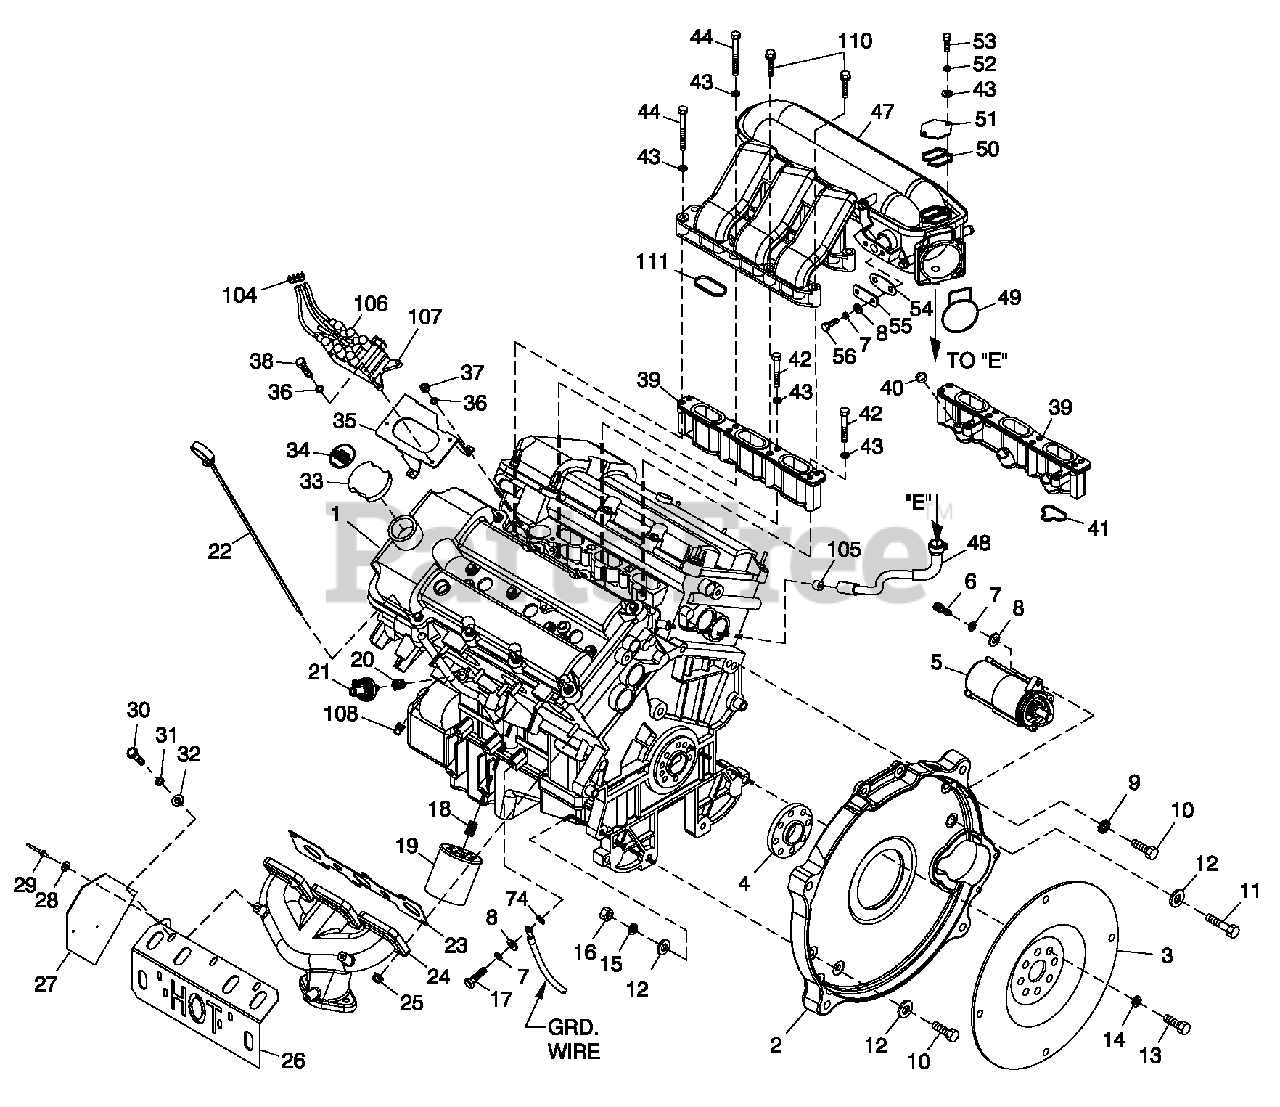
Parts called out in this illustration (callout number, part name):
1	ENGINE 3.0L G3 LS (RWD) MAKE
2	ADAPTER ENGINE
3	FLEX PLATE 2 POLE
4	SPACER FLEX PLATE
5	STARTER MOTOR 12V
6	SCREW SHC M8-1.25 X 30 G12.9
7	WASHERLOCK M8-5/16
8	WASHER FLAT 5/16-M8 ZINC
9	WASHER SHAKEPROOF EXT 7/16 STL
10	SCREW HHC M10-1.5X 45 G8.8 FT
11	SCREW HHC M10-1.5X 60 G8.8
12	WASHER FLAT 3/8-M10 ZINC
13	SCREW HHC M10-1.0X 25 G10.9
14	WASHER FLAT .45X1.00
15	WASHER LOCK M10
16	NUT HEX M10-1.5G8YEL CHR
17	SCREW HHC M8-1.25X 25 G8.8
18	ADAPTER OIL FILTER 3.0L
19	OIL FILTER
20	BSHG RDCR HEX 3/8 T O 1/8 GALV
21	SWITCH OIL PRESSURE 10 PSI 2 POL
22	DIP STICK OIL 3.0L
23	GASKET EXHAUST
24	MANIFOLD EXHAUST LH
25	NUT HEX FLWHIZ M8-1.25
26	HEAT SHIELD EXHAUST 3.0L INCLUDED WITH I/N 26.
27	REFLECTIVE HEAT SHIELD 3.0L
28	WASHER FLAT #6 ZINC
29	RIVET POP.125X.400 AL
30	SCREW HHC 1/4-20 X 1/2 SS
31	WASHER LOCK 1/4-M6SS
32	WASHER FLAT 1/4 SS
33	OIL FILLER CAP 3.0L
34	DECAL REFER T O OWNERS MANUAL
35	BRACKET COIL
36	WASHERLOCK M5
37	NUT HEX M5-0.8 G8 CLEAR ZINC
38	SCREW HHC M5-0.8X 25 G8.8
39	MANIFOLD INTAKE LOWER REWORK
40	PLUG EXPANSION 14 OD
41	GASKET INTAKE MANIFOLD LWR G3
42	SCREW HHC M6-1.0X 80 C8.8
43	WASHER FLAT 1/4-M6 ZINC
44	SCREW HHC M6-1.0X 120 C8.8
47	MANIFOLD INTAKE UPPER
48	ASSEMBLY H OSE PCV VALVE
49	GASKET INTAKE ADAPTER
50	GASKET IDLE AIR CONTRL ACT CVR
51	COVER IAC ACTUATOR
52	WASHER LOCK M6-1/4
53	SCREW HHC M6-1.0X16G8.8
54	EGR GASKET
55	COVEREGR
56	SCREW HHC M8-1.25X 20 G8.8
57	PLUG, EXPANSION 16MM
58	REWORK HARMONIC BAL 3.0L RWD
59	BELT SERPENTINE 71.04"
60	WATER PUMP 3.0L
61	HOSE WATER PUMP 3.0L
62	CLAMP HOSE #24 B1.06-2.00
63	REW ORK BREATHER TUBE 3.0L G3 LS
64	SCREW HHC M8-1.25X 65 G8.8
65	PULLEY GROOVED ENGINE IDLER
66	SPACER IDLER PULLEY 3.0L
67	SCREW HHC M6-1.0X 20 G8.8
68	SENSOR CRANKSHAFT SPEED 3.0L
69	WELDMENT IDLER BRACKET 3.0L
70	BOLT HEX FL HD M8-1.25X 28
71	SPACER .34X 1.00X.11 STL/ZC
72	SCREW HHC M8-1.25X 35 G8.8
73	SPARK PLUG (PLATINUM) .044 GAP
74	WASHER SHAKEPROOF EXT 5/16 STL
76	NUT HEX M8-1.25 G8 CLEARZINC
77	BRACKET DC ALTERNATOR LOWER
78	BRACKET TENSIONER
79	ALTERNATOR DC W/OUT PULLEY
80	SPACER DC ALTERNATOR PULLEY
81	PULLEY 132 OD DC ALTERNATOR
82	SCREW HHC M10-1.5X25G8.8
83	BRACKET THERMOSTAT 3.0L
84	NUT HEX M6 X 1.0 G8 YEL CHR
85	CLAMP HOSE #28 1.32-2.25
86	HOSE UPPR RAD REAR
87	ADAPTER THERMOSTAT
88	GASKET THERMOSTAT
89	MACHINING,THERMO STAT ADPTR
90	THERMOSTAT 195 DEG
91	SWITCH HI-TEMP 245D X 3/8 NPT
92	WASHER LOCK M5
93	SCREW HHTT M5-0.8X10BP
94	SCREW HHC M8-1.25X 80 G8.8
95	BARBED STR 1/2NPTX 3/4
96	CLAMP HOSE#10.56-1.06
97	H O SE CO OL 3/4 ID 20R3 (22" LG)
98	HOSE OIL DRAIN ASSY 21"
99	CLAMP HOSE .38-.87
100	BARBED EL 90 3/8 NPT X 3/8
101	ADAPTERM12-1.75X 3/8 NPT
102	WASHER NYL ON .50 X .87 X .06
103	SCREW HHC M10-1.5X35G8.8
104	RETAINER SPARK PLUG WIRE
105	RESTRICT OR PCV
106	SPARK PLUG WIRE SET
107	COIL IGNITION
108	PLUG STD PIPE 3/8 COUNTERSUNK
109	MANIFOLD EXHAUST RH
110	SCREW HHC M6-1.0 X 50 G8.8 (INCL. WITH I/N 47)
111	GASKET INTAKE MANIFOLD UP G3
112	RESTRICTOR COOLANT BYPASS
113	WASHER SHAKEPROOF EXT 1/4 STL
114	COOLANT X-OVER CASTING
115	SCREW HHC M6-1.0X 30 C8.8
